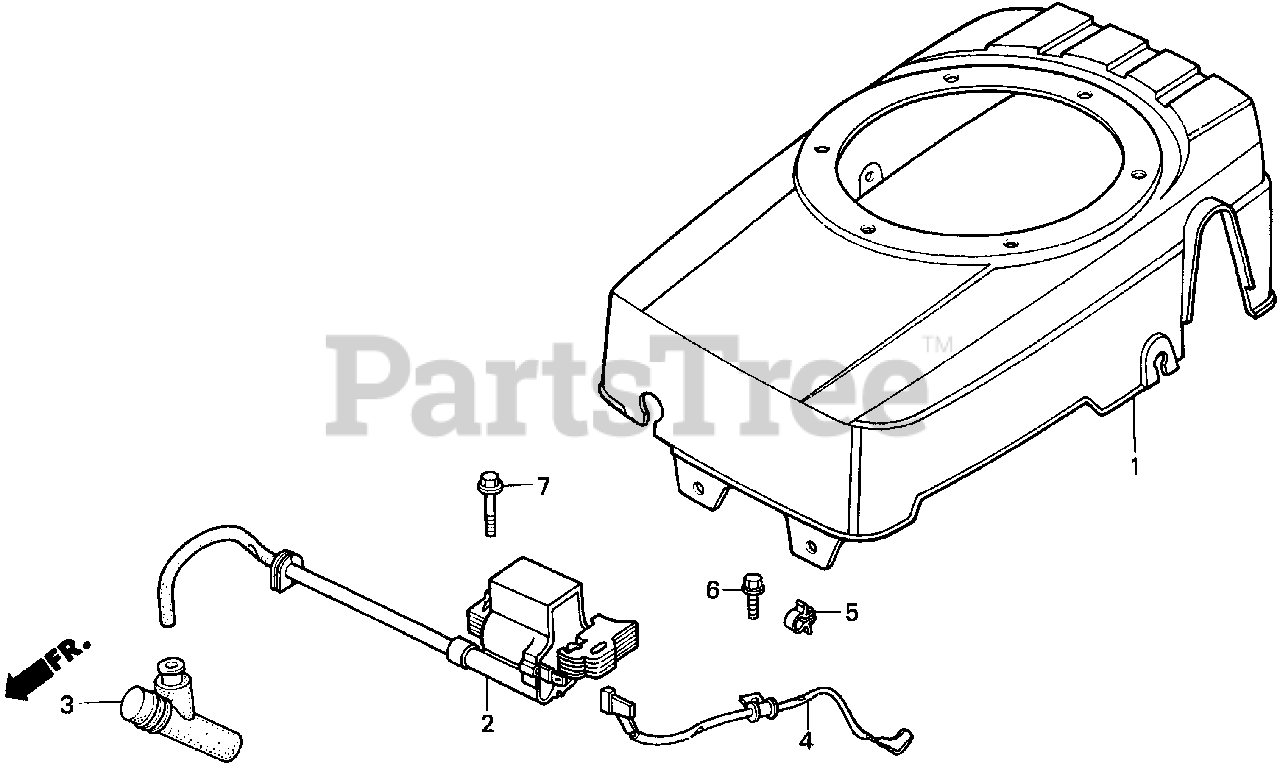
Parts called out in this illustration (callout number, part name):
1	COVER, FAN
2	COIL ASSY., IGNITION (NOT AVAILABLE)
2	COIL ASSY., IGNITION
3	TERMINAL ASSY., IGNITION
3	CAP ASSY., NOISE SUPPRESSOR
4	WIRE, STOP SWITCH
5	HOLDER, STOP SWITCH WIRE Use up to Engine SN 2056819.
6	BOLT, FLANGE (5X10)
7	BOLT, FLANGE (6X25) Use up to Engine SN 2056819.
